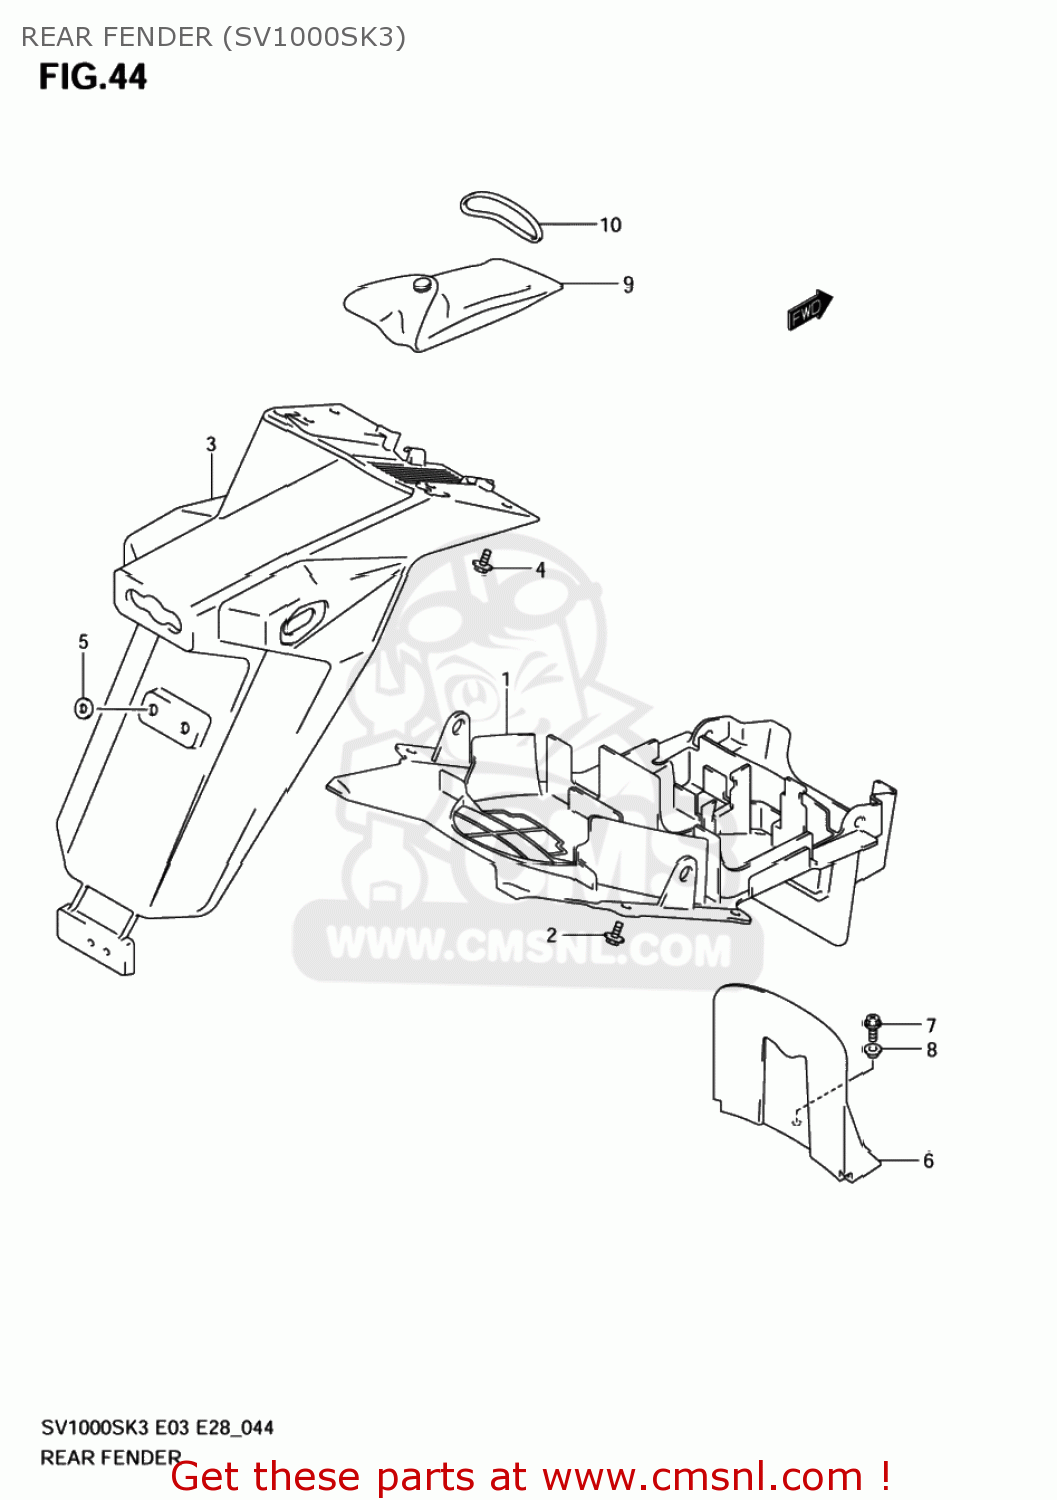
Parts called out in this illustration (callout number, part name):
1	FENDER,RR FR
2	BOLT 6X14
3	FENDER,RR RR
4	BOLT 6X14
5	WASHER
6	MUDGUARD,RR FENDER LWR
7	SCREW
8	WASHER
9	TOOL ASSY
10	O RING(D:3.5,ID:61)
